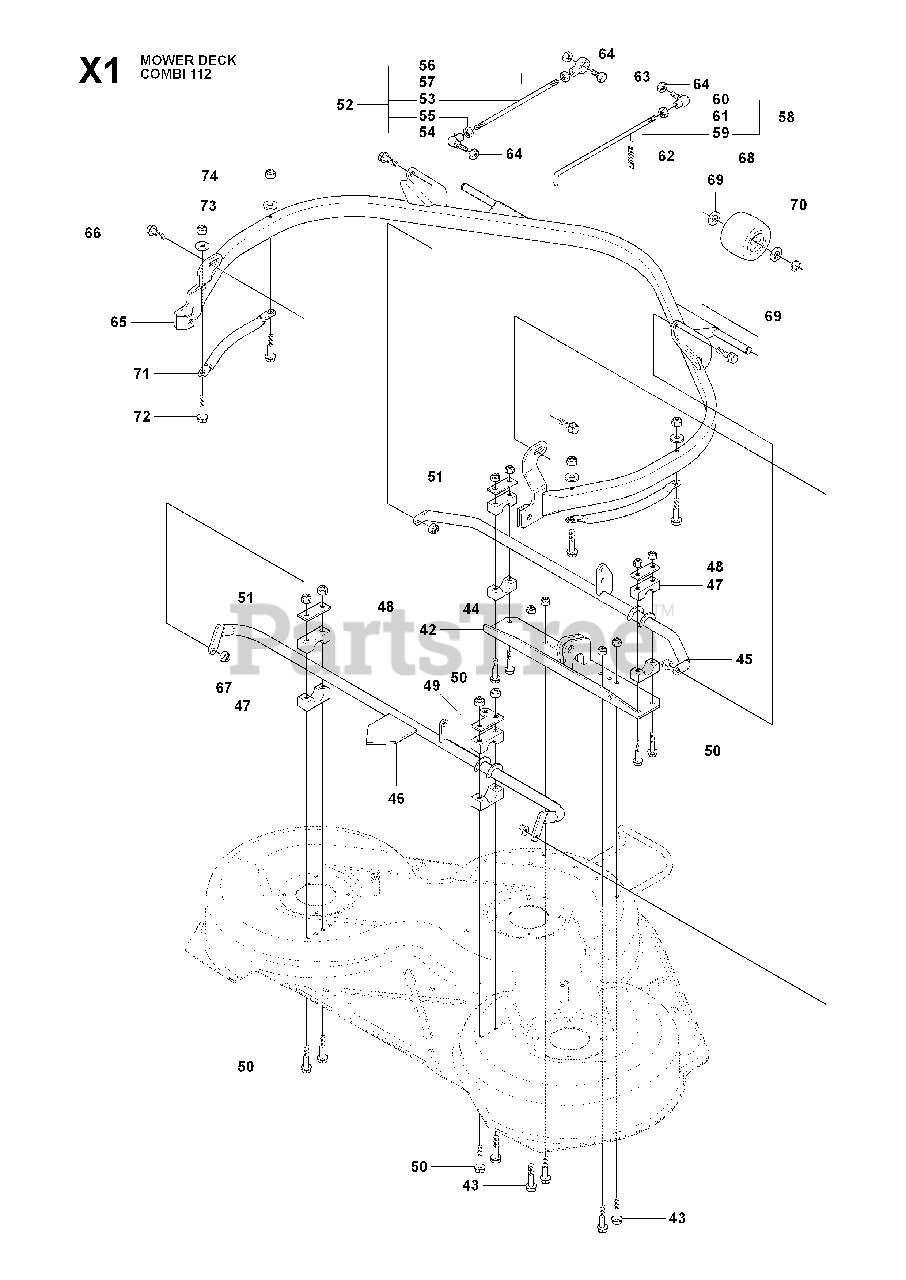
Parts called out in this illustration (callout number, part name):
44	LOCKNUT M8
51	LOCKNUT M8
52	PARALLEL RODY ASSY
58	CLUTCH ROD ASSY
67	LOCKNUT M8
68	DECK ROLLER, FRONT
70	RETAINING RING SGA 15
73	WASHER
74	LOCKNUT M6
